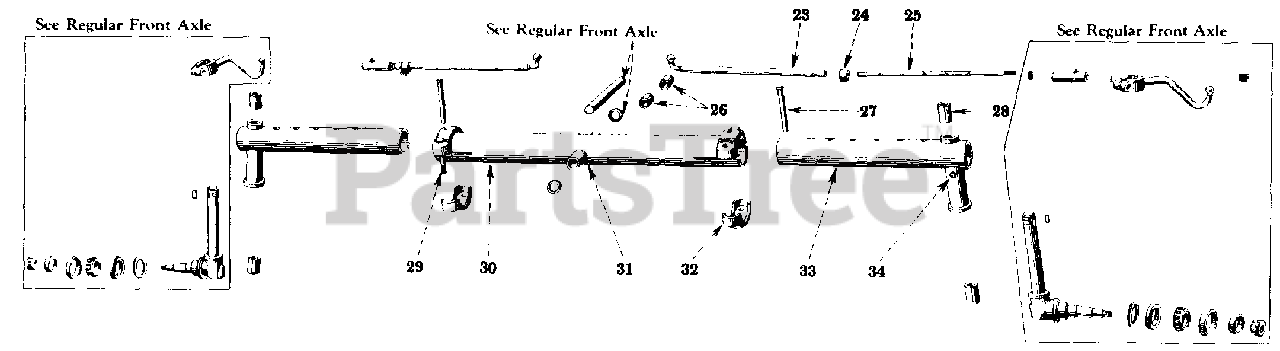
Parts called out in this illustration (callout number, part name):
23	TUBE, TIE ROD 14-3/4 IN. LONG
24	CLAMP, TIE ROD
26	BUSHING, FRONT AXLE PIVOT
27	PIN, FRONT AXLE CLAMP
28	BUSHING, STEERING KNUCKLE POST
29	SCREW, 1/2-20 X 3 HEX-HD CAP FRONT AXLE CLAMP
30	AXLE, FRONT
31	FITTING, 1/4-28 NS TAPER STR LUB
32	CLAMP, FRONT AXLE
33	EXTENSION, FRONT AXLE
34	FITTING, 1/4-28 NS TAPER STR LUB STEERING KNUCKLE POST
